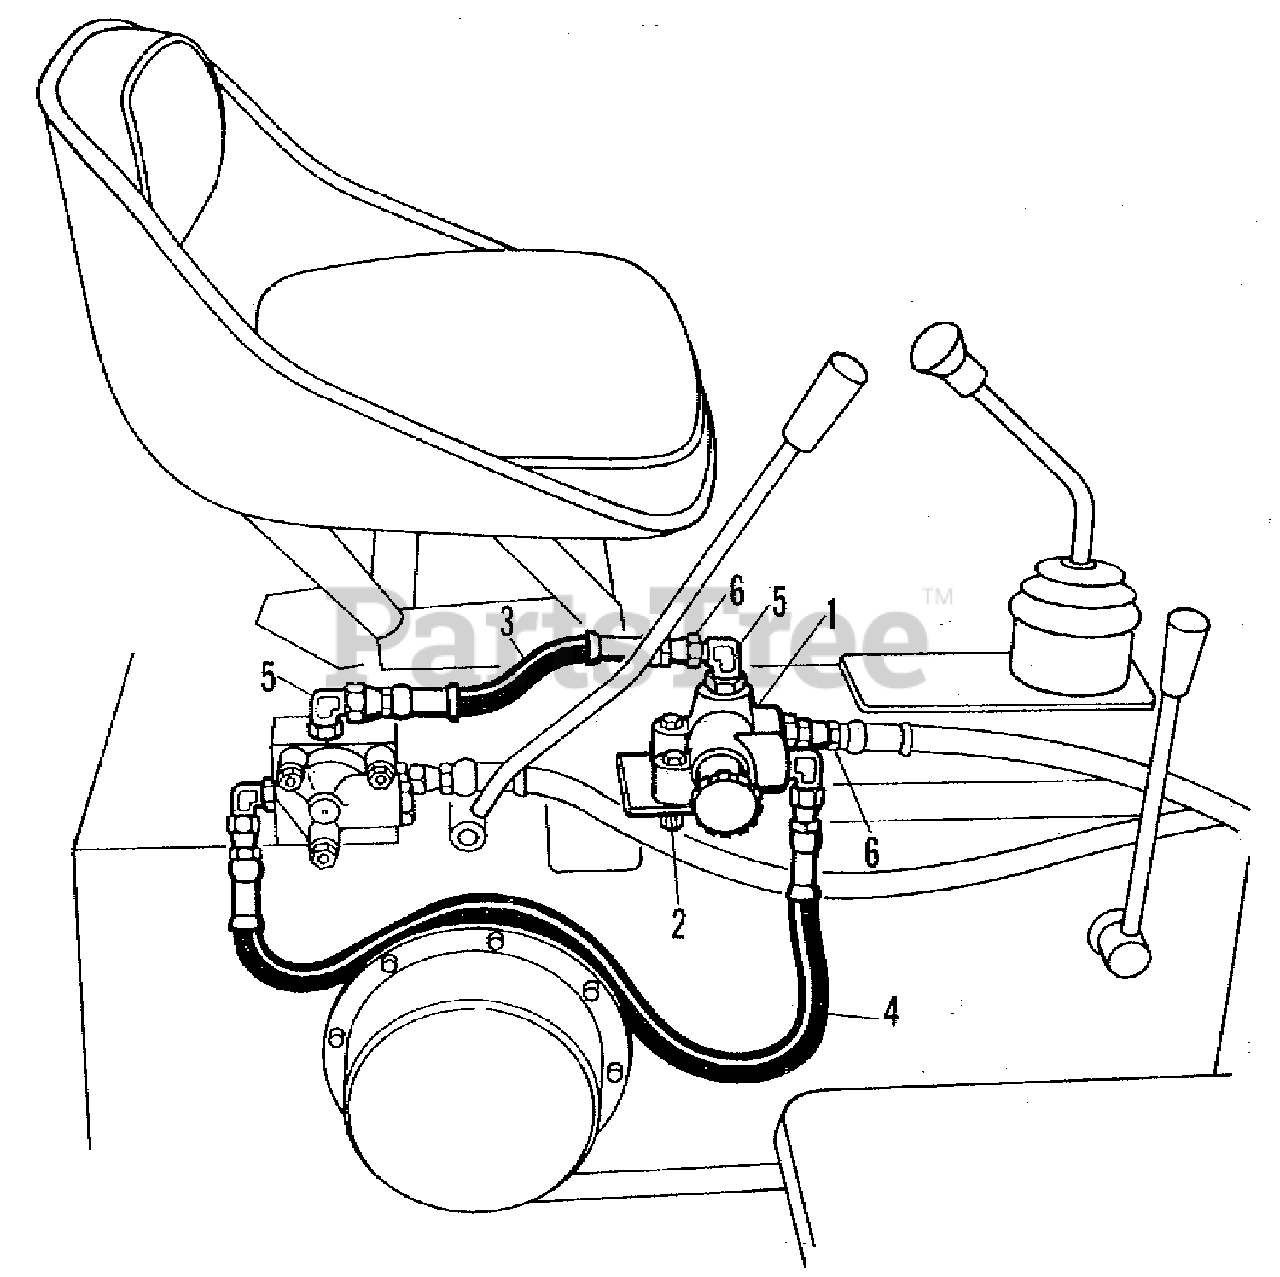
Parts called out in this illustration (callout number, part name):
1	VALVE ASSEMBLY, Selector
1	CAPSCREW, 5/16NC x 2
1	WASHER, Plain, 3/8 x 7/8 x 16 Ga.
1	LOCKWASHER, 5/16
1	NUT, 5/16NC
2	MOUNTING, Valve
3	HOSE ASSEMBLY, 9" Long (Selector Valve to Diverter Block)
4	HOSE ASSEMBLY, 28" Long (Selector Valve to Diverter Block)
5	ADAPTER, Elbow
6	CONNECTOR, Straight
